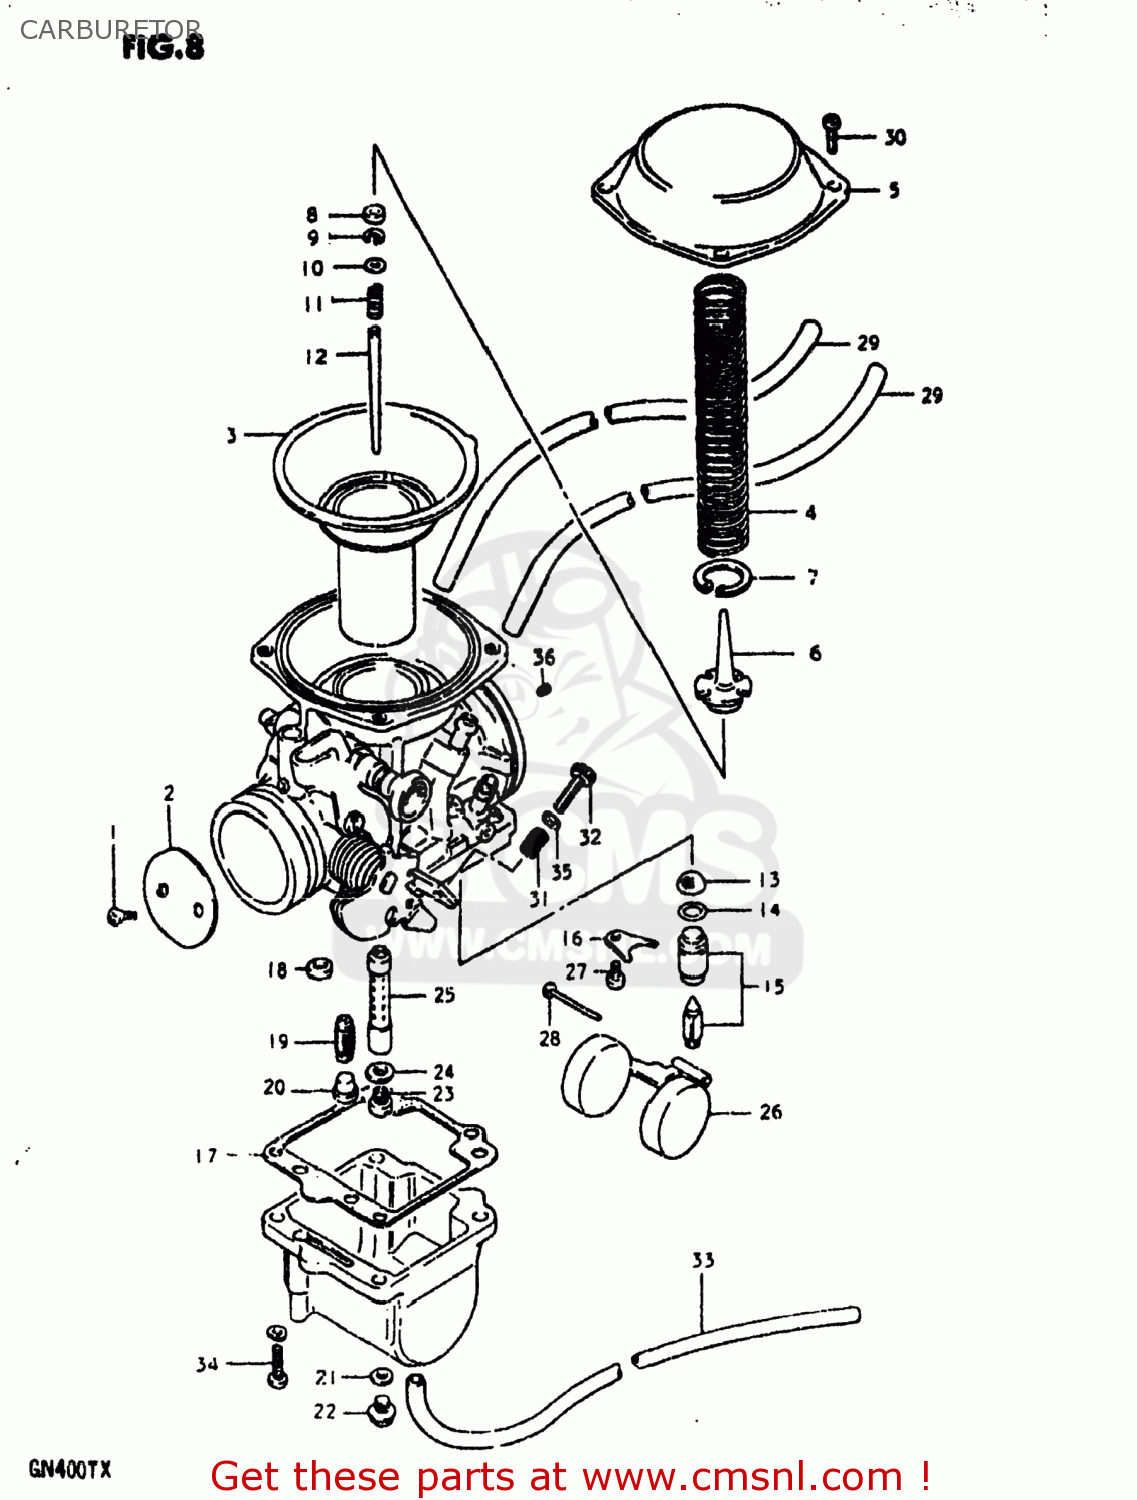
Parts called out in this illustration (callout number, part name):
1	SCREW
2	VALVE,THROTTLE (BUTTERFLY)
3	DIAPHRAGM
4	SPRING
5	COVER,DIAPHRAGM
6	HOLDER,GUIDE
7	E RING
8	RING
9	CLIP,NEEDLE
10	WASHER
11	SPRING
12	NEEDLE JET
13	FILTER
14	O RING
15	VALVE ASSEMBLY,NEEDLE
16	PLATE
17	GASKET,FLOAT CHAMBER (NAS)
18	GASKET (NAS)
19	JET,PILOT(42.5)
20	PLUG,NEEDLE JET
21	GASKET (NAS)
22	PLUG,DRAIN
23	JET,MAIN(132.5)
24	WASHER
25	JET,NEEDLE
26	FLOAT
27	SCREW 4X6
28	PIN,FLOAT
29	HOSE
30	SCREW
31	SPRING
32	SCREW,THROTTLE STOP
33	HOSE
34	SCREW
35	WASHER
36	JET
